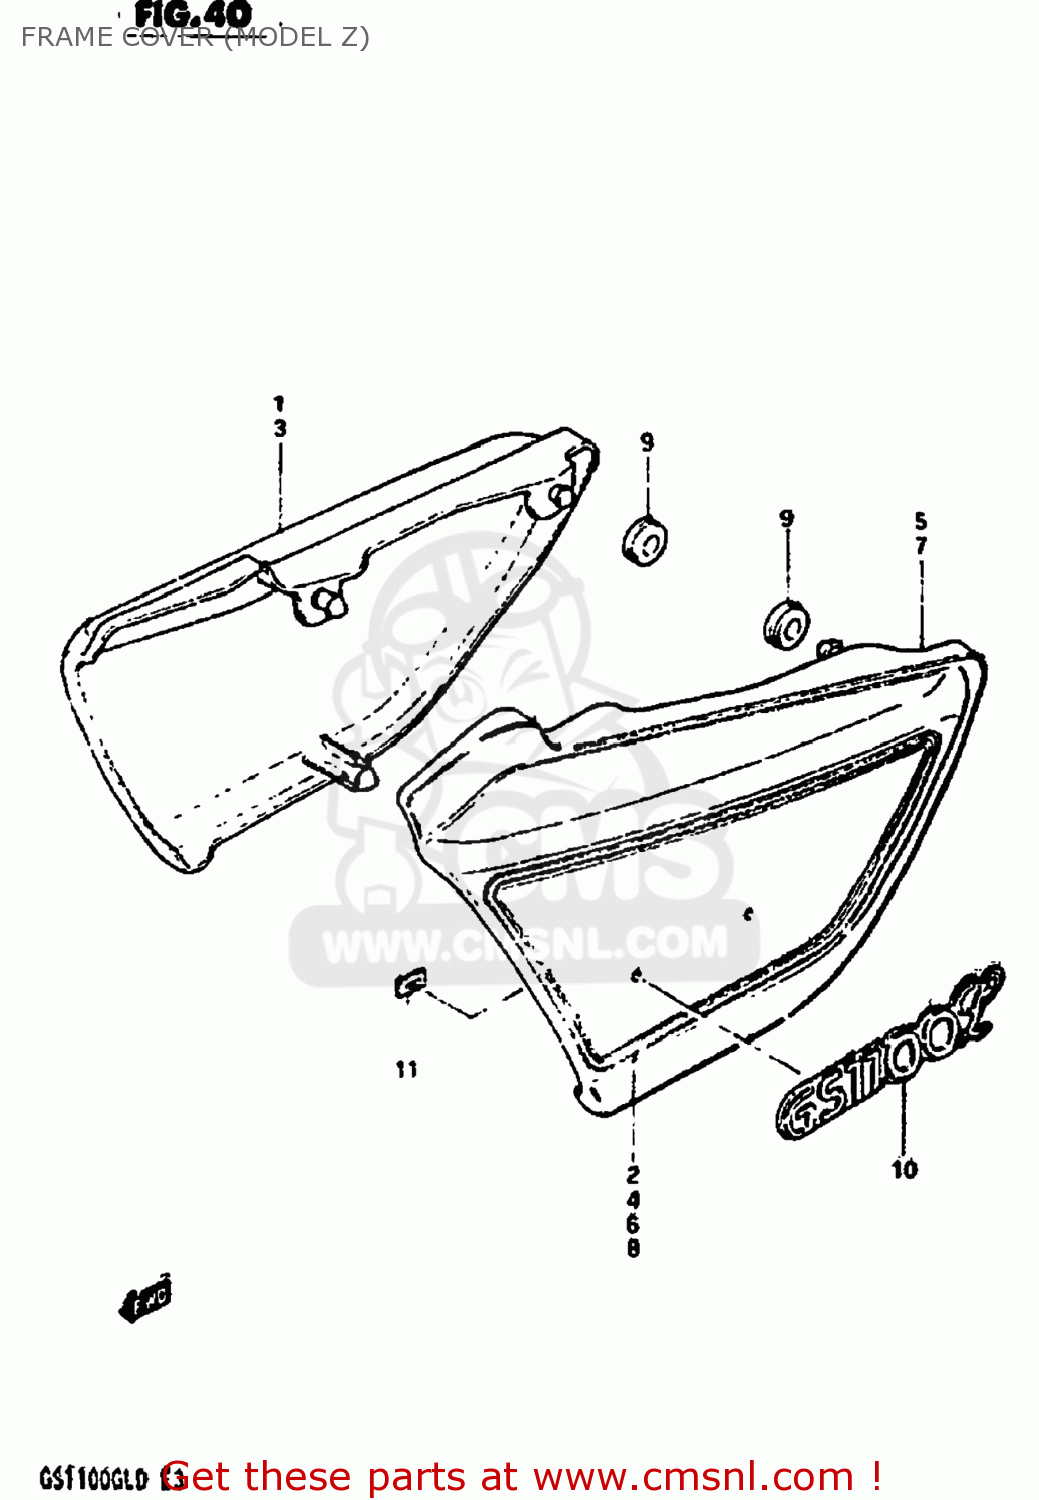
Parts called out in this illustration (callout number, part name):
1	COVER,FRAME,RIGHT
2	TAPE,FRAME COVER
3	COVER ASSEMBLY,FRAME,RIGHT
4	TAPE,FRAME COVER
5	COVER,FRAME,LEFT
6	TAPE,FRAME COVER
7	COVER ASSEMBLY,FRAME,LEFT
8	TAPE,FRAME COVER
9	CUSHION
10	EMBLEM,FRAME COVER
11	NUT
